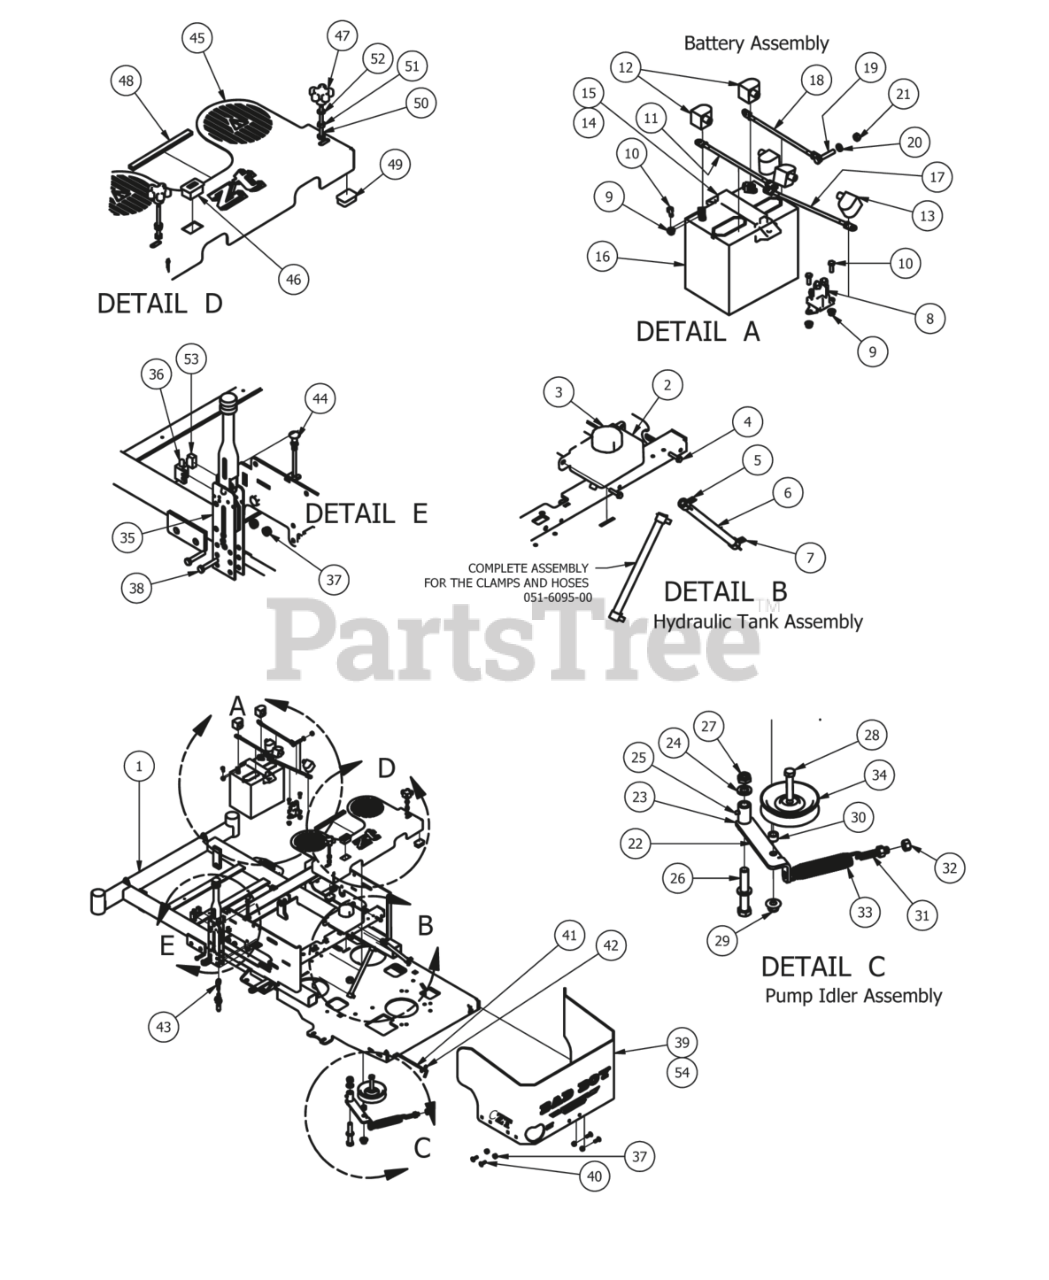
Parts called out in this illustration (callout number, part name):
2	ZT Hydraulic Tank
3	Hydraulic Tank Cap
4	1/4 x 1 Hex Head tek screw
5	3/8 hose clamp
6	3/8 clear hose price per foot
7	1/2 Hose Clamp
9	1/4-20 Hex Flange Nuts Zinc w/Serrations
10	1/4-20 x 3/4 GR 5 Hex Bolts Zinc
11	12 in red battery cable
12	Black Boot For ground cable
14	Hold Down Assembly
15	Battery Hold Down
16	ZT Battery
17	24 in red battery cable
18	Ground Cable
19	5/16" x 1 3/4" Hex Bolt
20	5/16" Lock Washer
22	Pump Idler Assembly Components 23,25,28,29,30,34
23	Pump Idler Bracket
24	.635 ID Plastic Washer
25	1/4" Drive in Grease Fitting
26	5/8" x 4" Hex Bolt
27	5/8" Nylock (1/2 Jam)
28	1/2-13 x 2 3/4 GR 5 Bolt
29	1/2-13 Nylon Flange Nut-Orange
30	1/2 x 1/2 Spacer
31	All Thread-pump Idler Tensioner
32	1/2" Hex Nut
33	2009 Deck/Pump Idler Spring
34	4 3/4" Idler Pulley
35	Brake Handle Kit
36	Safety Switch
37	5/16-18 Nylon Flange Nut
38	5/16" x 1 3/4" Hex Bolt
39	ZT Rear plate 23hp
40	5/16" x 1" Carriage Bolt
41	ZT Neutral level rod 2011
43	Brake Cable
45	ZT Fan Cover
46	Tachometer
47	5/16" Knob
48	Rubber Trim
49	Square 3/4 Plug-SQR07-1620
50	18x3 GR5 Hex bolt zink
52	5/16" Lock Washer
53	Brake Plunger Stop
54	CZT Rear Cover FS-730V Kawasaki
